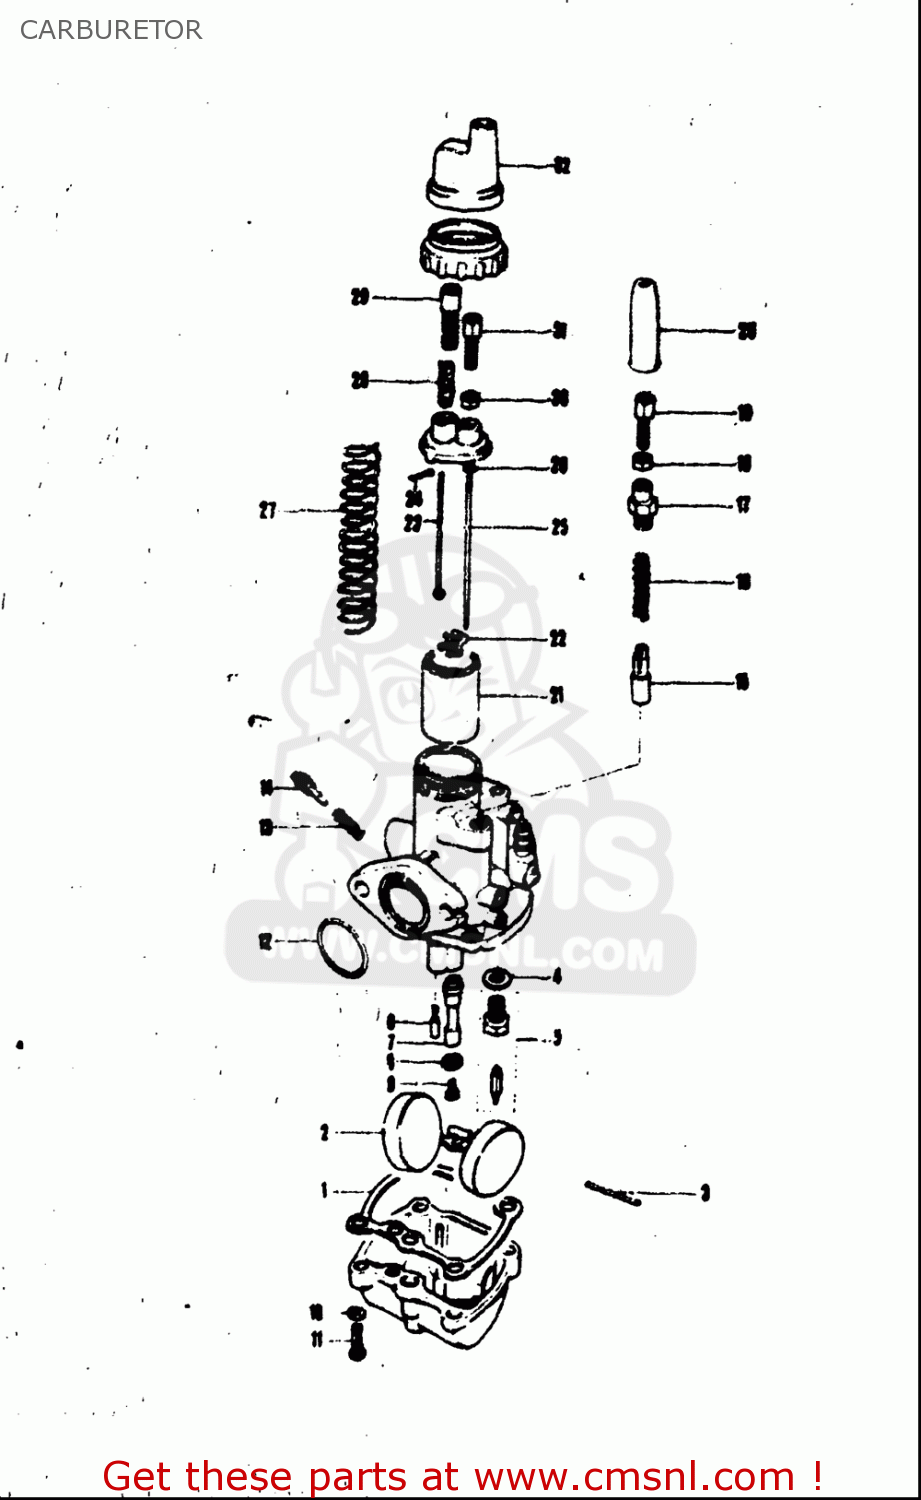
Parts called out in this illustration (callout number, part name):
2	FLOAT
4	GASKET,NEEDLE VALVE (NAS)
5	VALVE ASSY,NEEDLE
6	JET,PILOT
7	JET,NEEDLE
8	WASHER
9	JET,MAIN (95)
10	WASHER,LOCK
11	SCREW
12	O RING,OUTLET
13	SPRING
14	SCREW,PILOT AIR
16	SPRING
17	CAP
18	NUT
19	ADJUSTER,CABLE
26	CLIP
27	SPRING,THROTTLE VALVE
28	SPRING,THROTTLE SCREW
29	SCREW,THROTTLE VALVE ADJUST
30	NUT
31	ADJUSTER,CABLE
